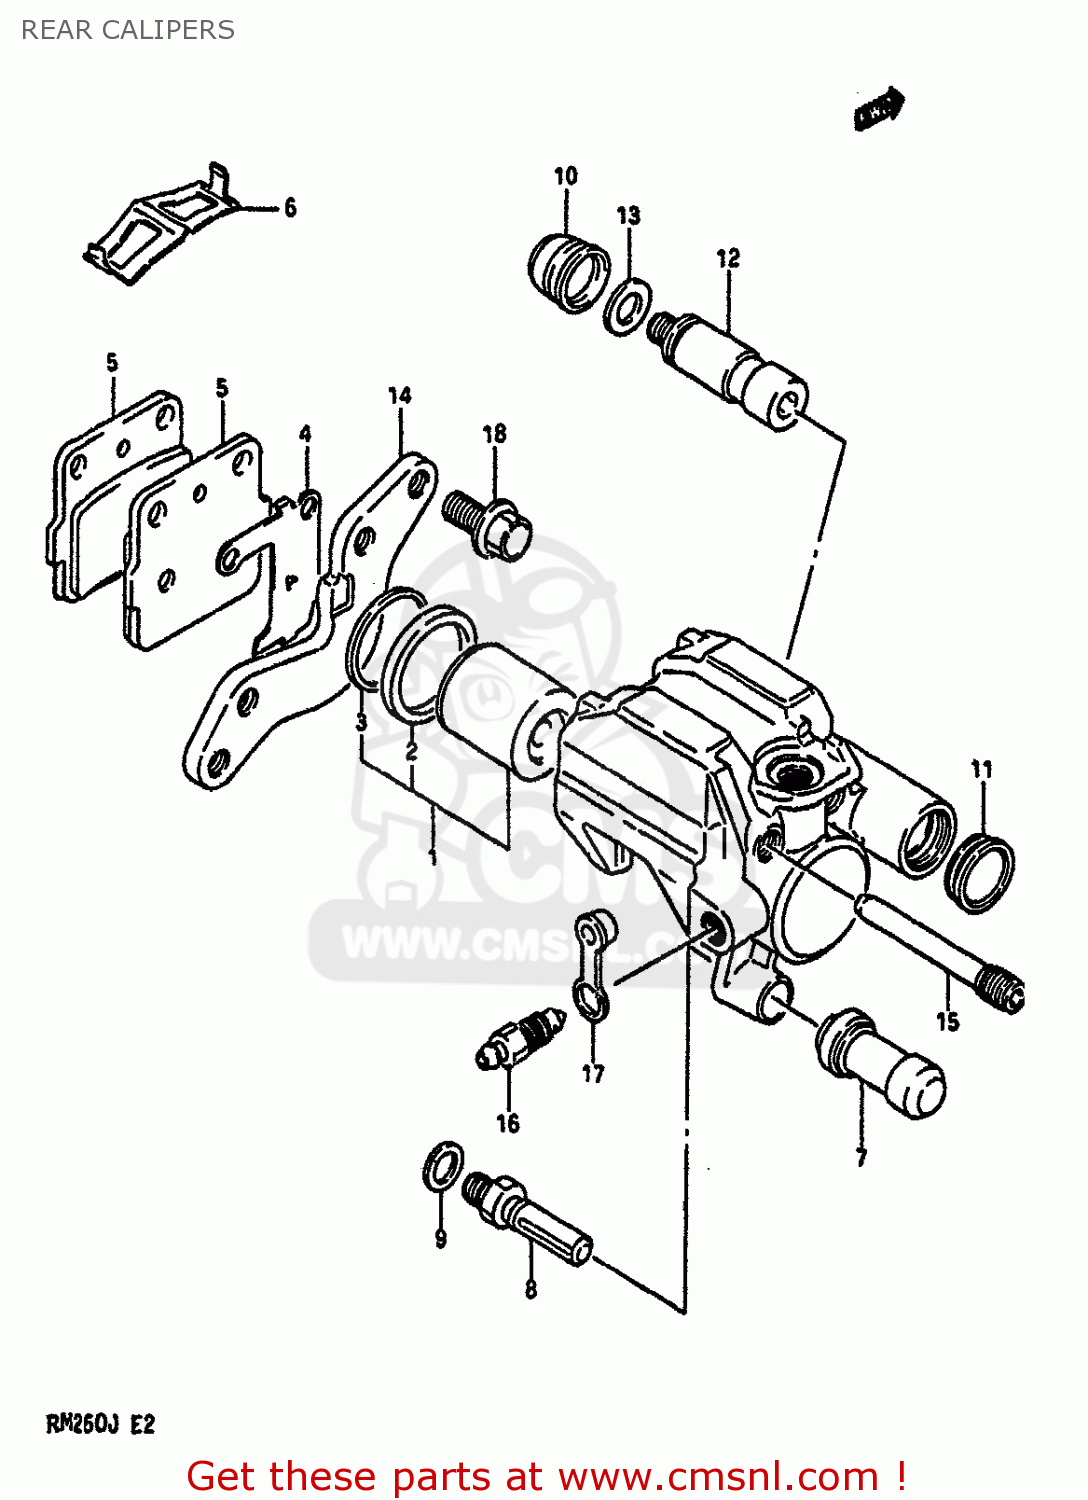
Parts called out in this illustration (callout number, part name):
1	PISTON SET
2	SEAL,PISTON
3	SEAL,DUST
4	SHIM
5	PAD (NAS)
6	SPRING,PAD
7	BOOT
8	BOLT,PIN
9	WASHER,WAVE
10	BOOT,PIN
11	DUST SEAL
12	PIN,SLIDE
13	SPRING,FRICTION
14	BRACKET
15	PIN
16	BLEEDER
17	CAP,BLEEDER
18	BOLT L:21
